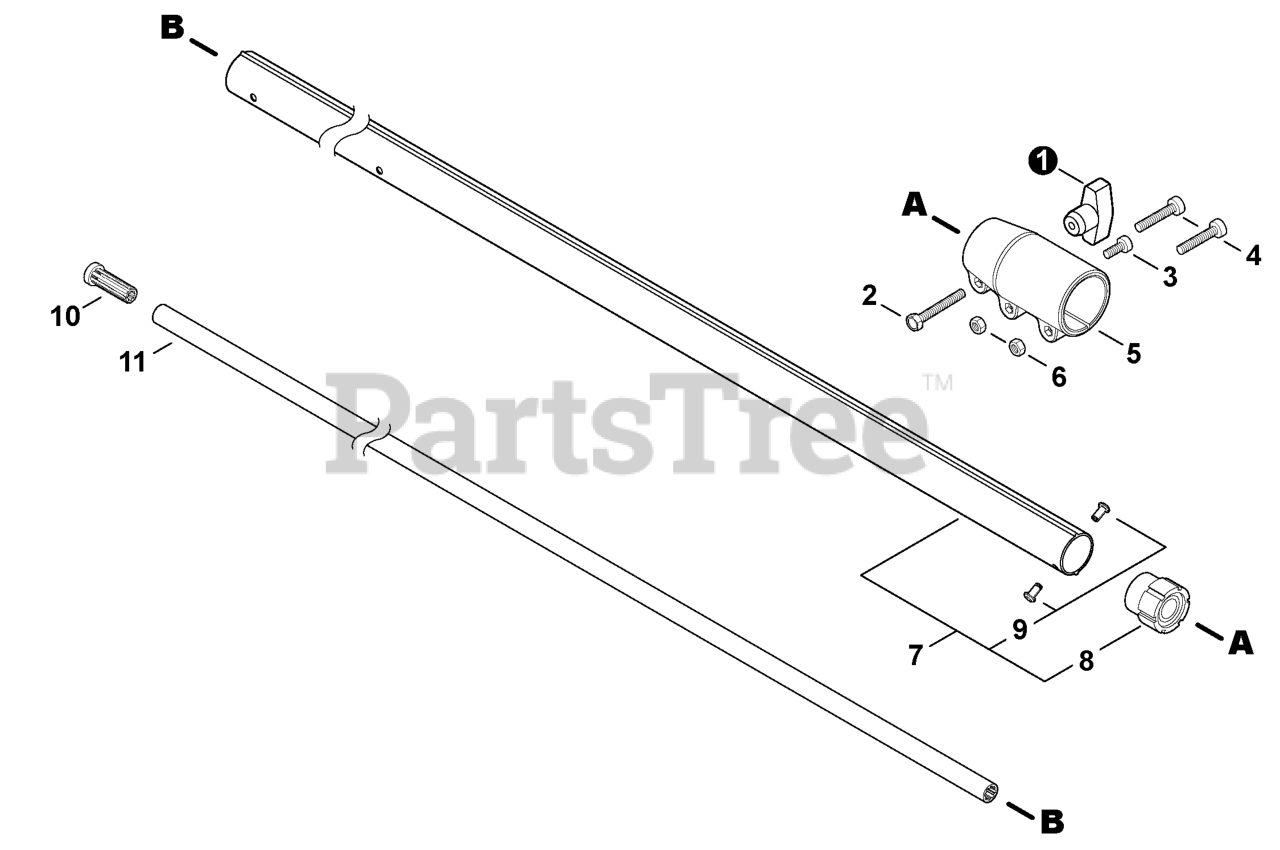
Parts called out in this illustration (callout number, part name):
1	THUMBSCREW
2	BOLT 6x25
3	BOLT, TORX 5x12
4	BOLT, TORX 5x20
5	COUPLING
7	MAIN PIPE ASSY - BLACK
8	HOLDER ASSY, BEARING
11	DRIVESHAFT - UPPER
